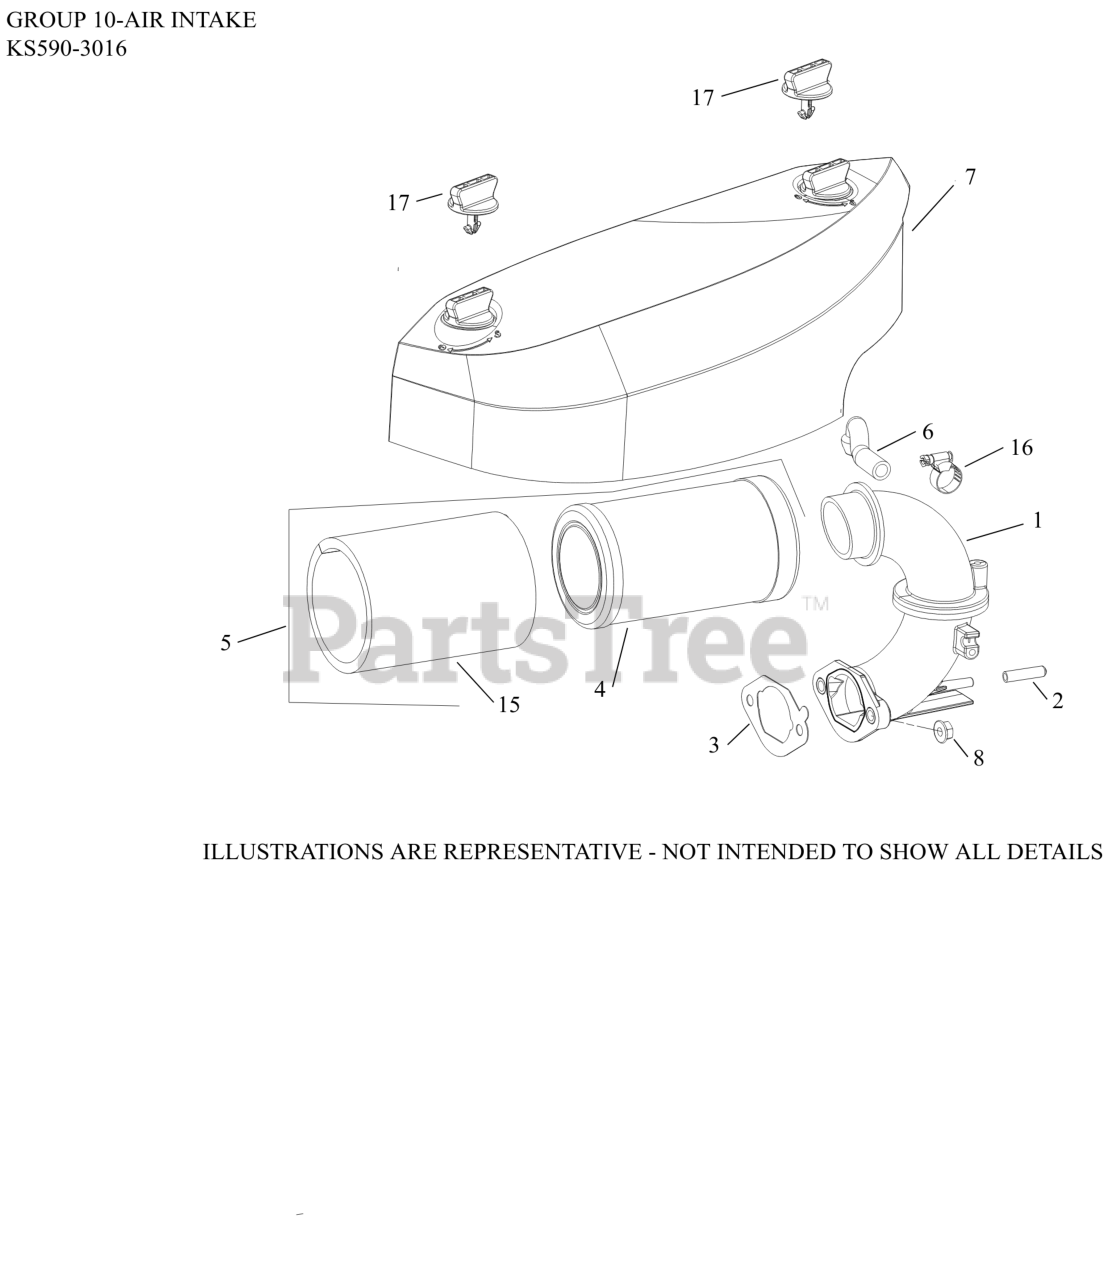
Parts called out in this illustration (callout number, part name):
1	ADAPTER, AIR CLEANER ASSY
2	CAP, MASKING
3	GASKET, CARBURETOR
4	ELEMENT, AIR FILTER
5	AIR FILTER KIT (STD)
6	HOSE, BREATHER
7	COVER, AIR CLEANER ASSY
8	NUT, FLG M6X1.0
15	ELEMENT, PRE-CLEANER
16	CLAMP, HOSE (KM)-USE 25 237 31-S
17	KNOB, AIR CLEANER COVER
